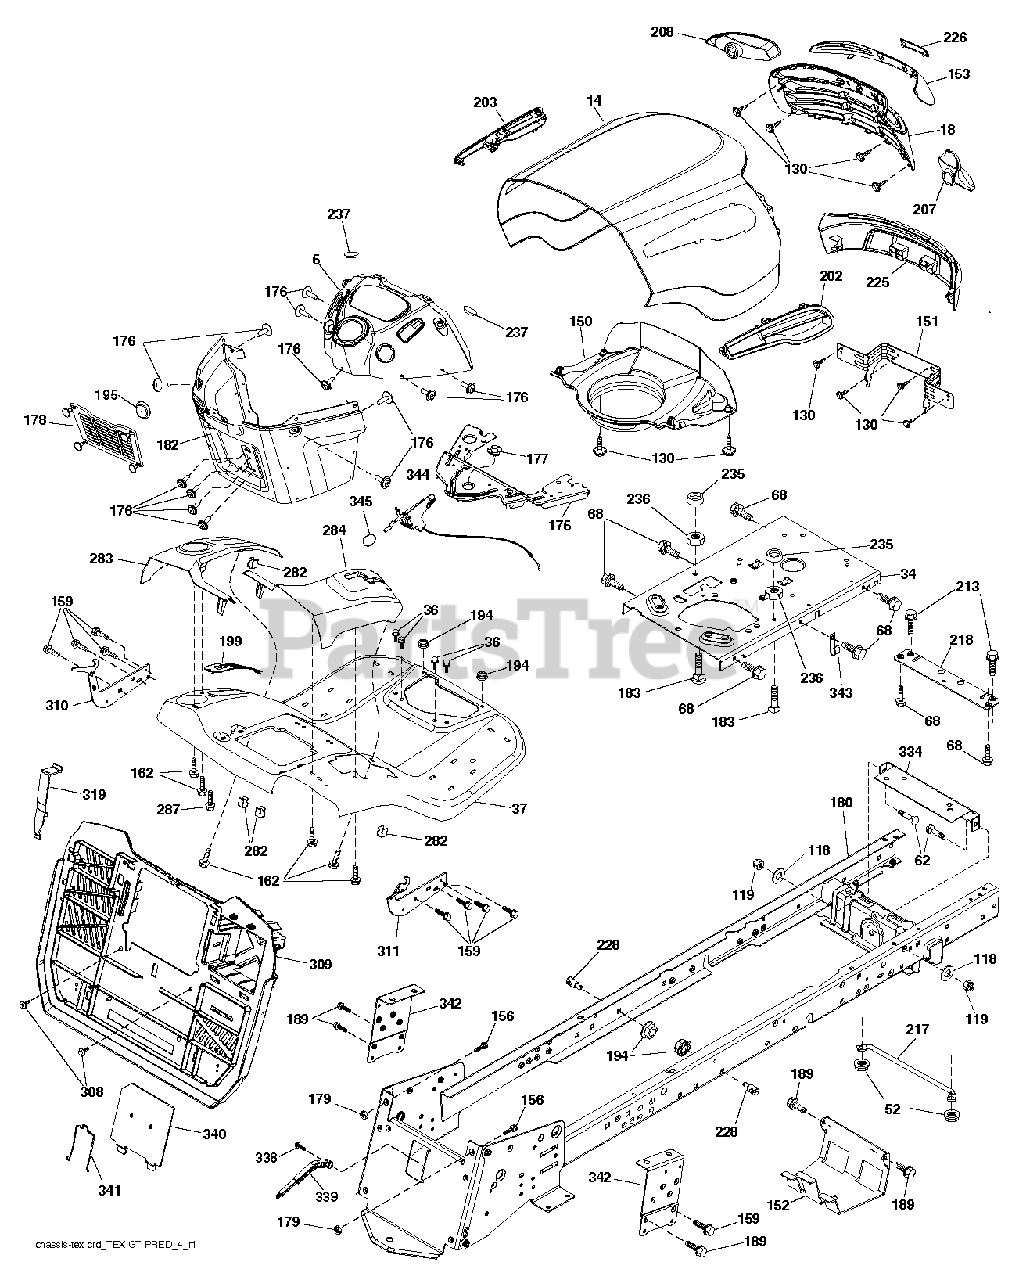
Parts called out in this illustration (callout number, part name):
36	SCREW 5/16"
52	LOCKNUT
119	LOCKNUT
130	SCREW.#10 X 0.750.BOS THREAD
150	PREDATOR.YT.GT.HOOD.A
151	BRACKET PIVOT
152	SHIELD BROWNING
156	BOLT
159	SCREW, 3/8-16X3/4
162	SCREW.HI-LO.CONSOLE
175	PLATE.CROSSMEMBER.HUSQ
176	SCREW.#10-24X5/8.RN.QU
177	BUSHING,STEERING
178	CARGO.ASM.NET.TXGT.W/C
183	BOLT.5/16-18X1-1/4 FULL THD
189	SCREW
194	NUT LOCK HEX FLANGE 5/16-18
195	PLUG.HOLE.DASH.LOWER.12V.BLK
213	BOLT
217	ROD.PIVOT.HOOD
218	X-PIECE.HOOD.STOP.NON/
228	STUD.FASTNER.W/ANTI-ROTATE
235	SPACER FENDER
236	NUT.CENTERLOCK.5/16-
237	PLUG.MOUNT.CARGO.BLK
282	CLIP.RETAINER.CONSOLE.LT.HUSQ
308	BOLT, 5/16-18 X 1 3/4
